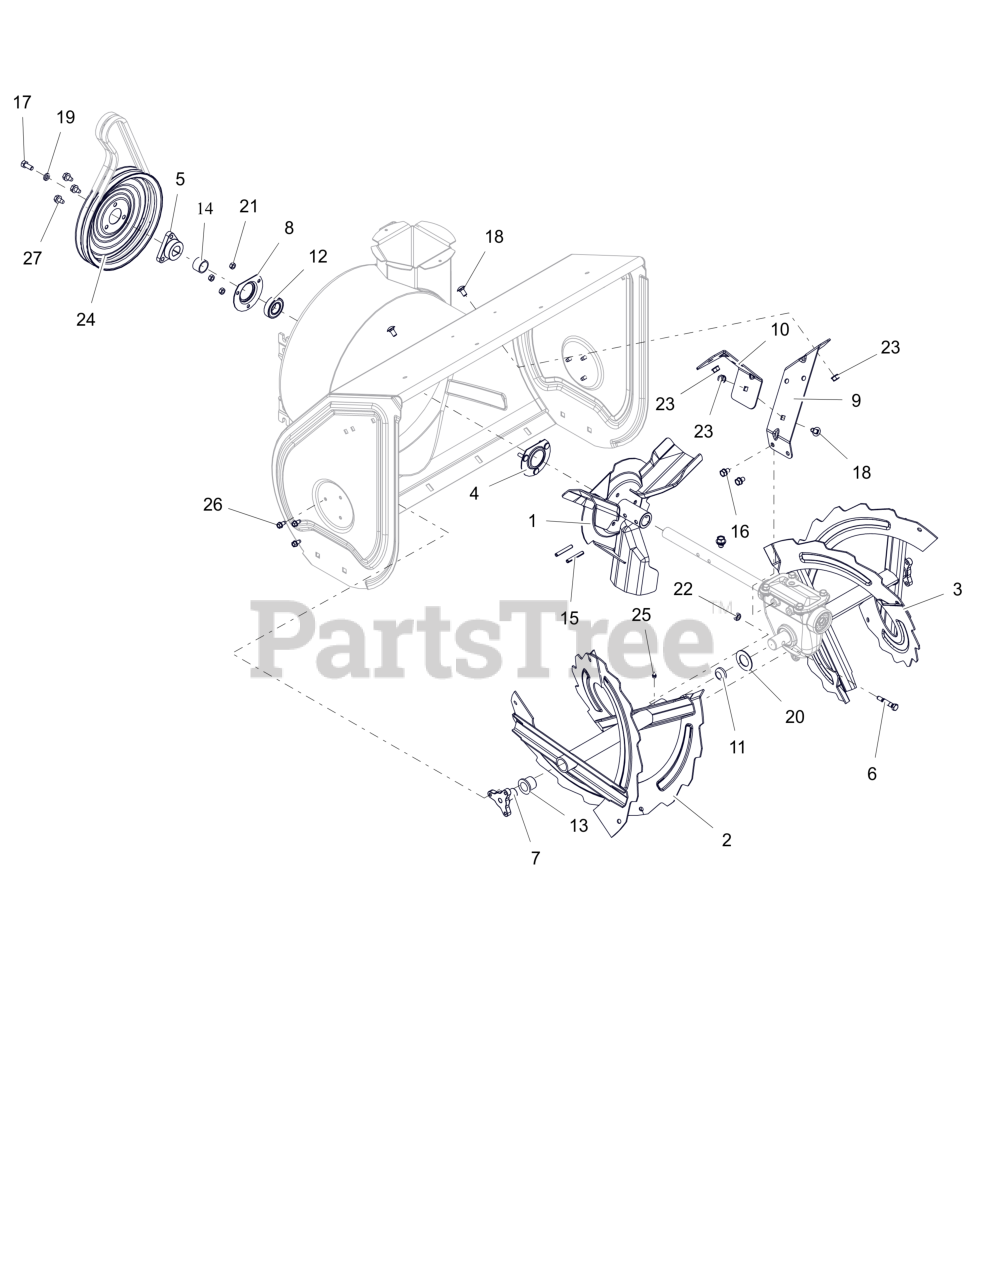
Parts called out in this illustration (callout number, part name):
1	IMPELLER, 3 BLADE-14"
2	RAKE, RH W/ZERK - 28"
3	RAKE, LH W/ZERK - 28"
4	BEARING FLANGE
5	PULLEY HUB, D-BORE .87 PRO
6	SHEAR BOLT SERVICE ASSEMBLY
7	SUPPORT, RAKE BUSHING
8	BEARING FLANGE
9	BRACKET, GEARCASE SUPPORT - LH
10	BRACKET, GEARCASE SUPPORT - RH
11	PLUG, RAKE TUBE
12	BRG-BALL .876 X 1.750 X .50
13	BSHG-FLG, NY.778 ID X 1.018 OD
14	BSHG,SPCR .895X1.065X.693
15	PIN-ROLL .250X1.75
16	BLT, SEMS .31-18X.50 G5 ZCC
17	BLT, HEX .31-24X.750 G5 ZCC
18	BLT,RHSSN.31-18X.625 G5 ZCCP30
19	WSHR, LK-HVY .312X.097 ZCC
20	WSHR- FLT 1.010X1.755X.062 ZCC
21	NUT,LK-CTR .25-20 GA ZCC
22	NUT,LK-CTR .31-18 GA ZCC
23	NUT-LK-TOP-FLG .312-18 GF ZCC
24	PULLEY, SPIN FORM DUAL GROOVE
25	ZERK,FITTING .25X.125 DRIVE IN
26	SCR-TAP .25-20X.50 HWH ZCC
27	SCR,TAP .312-18X.50 HWH TR ZCC
